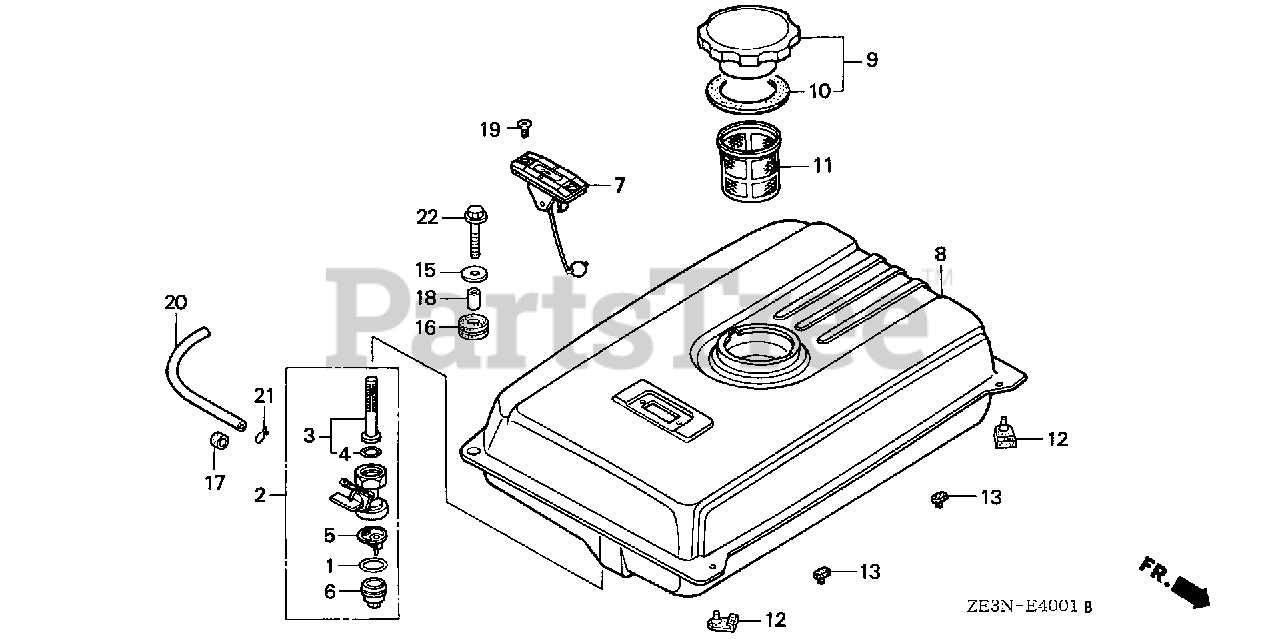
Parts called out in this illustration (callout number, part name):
1	GASKET, FUEL STRAINER CUP
2	PETCOCK ASSY.
3	SCREEN, FUEL STRAINER
4	O-RING (9X1.3)
5	FILTER, CUP
6	CUP, FUEL STRAINER
7	METER ASSY., FUEL
8	TANK, FUEL *T68* (TSURUI BLUE)
9	CAP, FUEL TANK
10	GASKET, FUEL FILLER CAP
11	FILTER, FUEL
12	RUBBER, TANK MOUNTING
13	STOPPER, DISCHARGE GUARD
15	WASHER, TANK RUBBER
16	CUSHION, TANK RUBBER
17	RUBBER, FUEL TUBE
18	COLLAR, TANK RUBBER
19	SCREW, FLAT (5X10)
20	BULK HOSE, FUEL (4.5X3000) (4.5X150)
21	CLIP, TUBE (B8)
22	BOLT, FLANGE (6X22)
